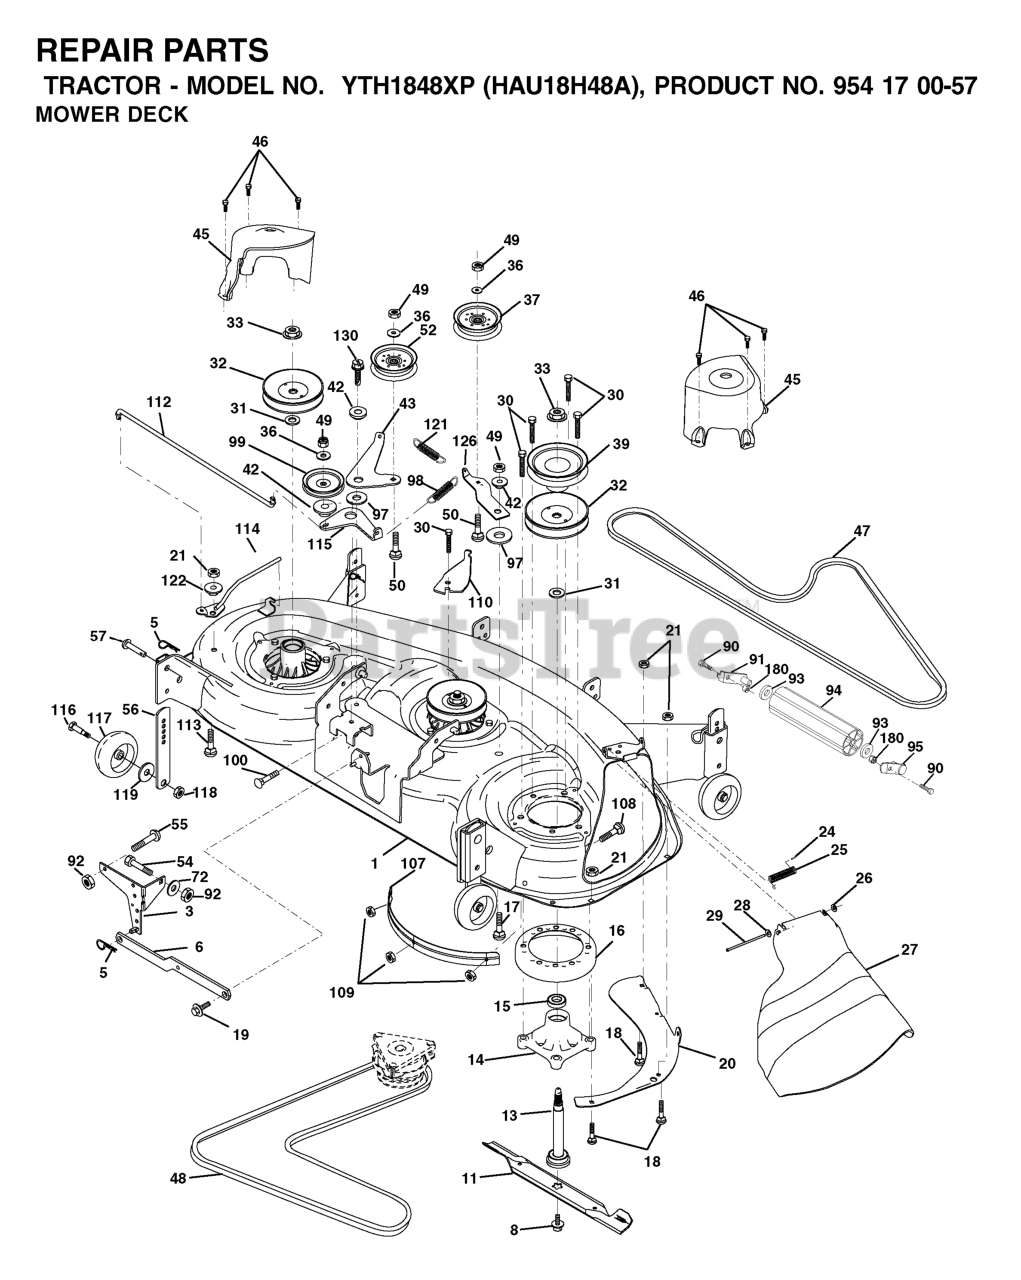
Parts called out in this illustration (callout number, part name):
1	Tension Asm Relief Lever
3	BRKT ASM SWAY BAR
5	RETAINER-SPRNG RB
6	REAR SUSP ARM
8	BOLT 7/16 ASM BLADE
11	BLADE
13	SHAFT ASM W/LOWER BEARING
14	HOUSING, MANDREL 48"
16	STRIPPER.MANDREL.ROUND.BLACK
17	BOLT
18	BOLT
19	BOLT SHD 5/16-18
20	BAFFLE, VORTEX MWR
21	LOCKNUT
24	CAP-SLEEVE LT
25	SPRING, TORSION
26	NUT PUSH M
27	SHIELD, DEFLECTOR MOWER
28	Washer 11/32 x 5/8 x 16 Ga SD
29	ROD.HINGE
30	SCREW THDROL ROLLING WASHER HD
31	WASHER
32	PULLEY, MANDREL
33	NUT, FLG TOPLOCK 9/16"
36	WASHER
37	PULLEY.IDLER.FLAT
39	PULLEY.DRIVEN.DECK.48'
42	SPACER RETAINER
43	ARM, IDLER SECONDARY
45	COVER, MANDREL DECK
46	SCREW.1/4-20X5/8
47	V-BELT, MWR SECONDARY
48	V-BELT PRIMARY 48"
50	BOLT.3/8-16X1.50
52	PULLEY.IDLER.FLAT.46.PR.DR.
55	BOLT D
56	BAR.ADJUST.WHEEL.ANTI.SCALP.BL
57	RIVET.PIN.HEAD.YELLOW.
72	WASHER
90	BOLT RB
91	BRKT ASM NOSEROLLER(L)48"
92	NUT
93	Washer 1 17/32 X 7/8 X 16 Ga
94	NOSE ROLLER 48"
95	BRKT, ASM NOSEROLLER(R)48
97	HARDENED WASHER
98	SPRING PRIMARY DRIVE
99	PULLEY,IDLER"V"
107	BAFFLE.VAC.EDGE.MOWER.48"
109	NUT.CROWNLOCK.1/4
110	ARM, SPRING SECONDARY
112	LEVER, TENSION RELIEF LINK
114	LEVER ASM, TENSION RELIEF
115	ARM, SPRING TENSION RELIEF
116	BOLT, SHOULDER
117	WHEEL GAGE DONUT
118	LOCKNUT
119	WASHER.5/16.FLAT.STE.STD.
121	SPRING.DRIVE.SECONDARY.48".DEC
122	BUSHING, PIVOT TENSION RELIEF
126	ARM, IDLER PRIMARY DECK
130	SCREW 3/8-16X1
180	NUT.71038.31-18.HEX.NYLOCK
